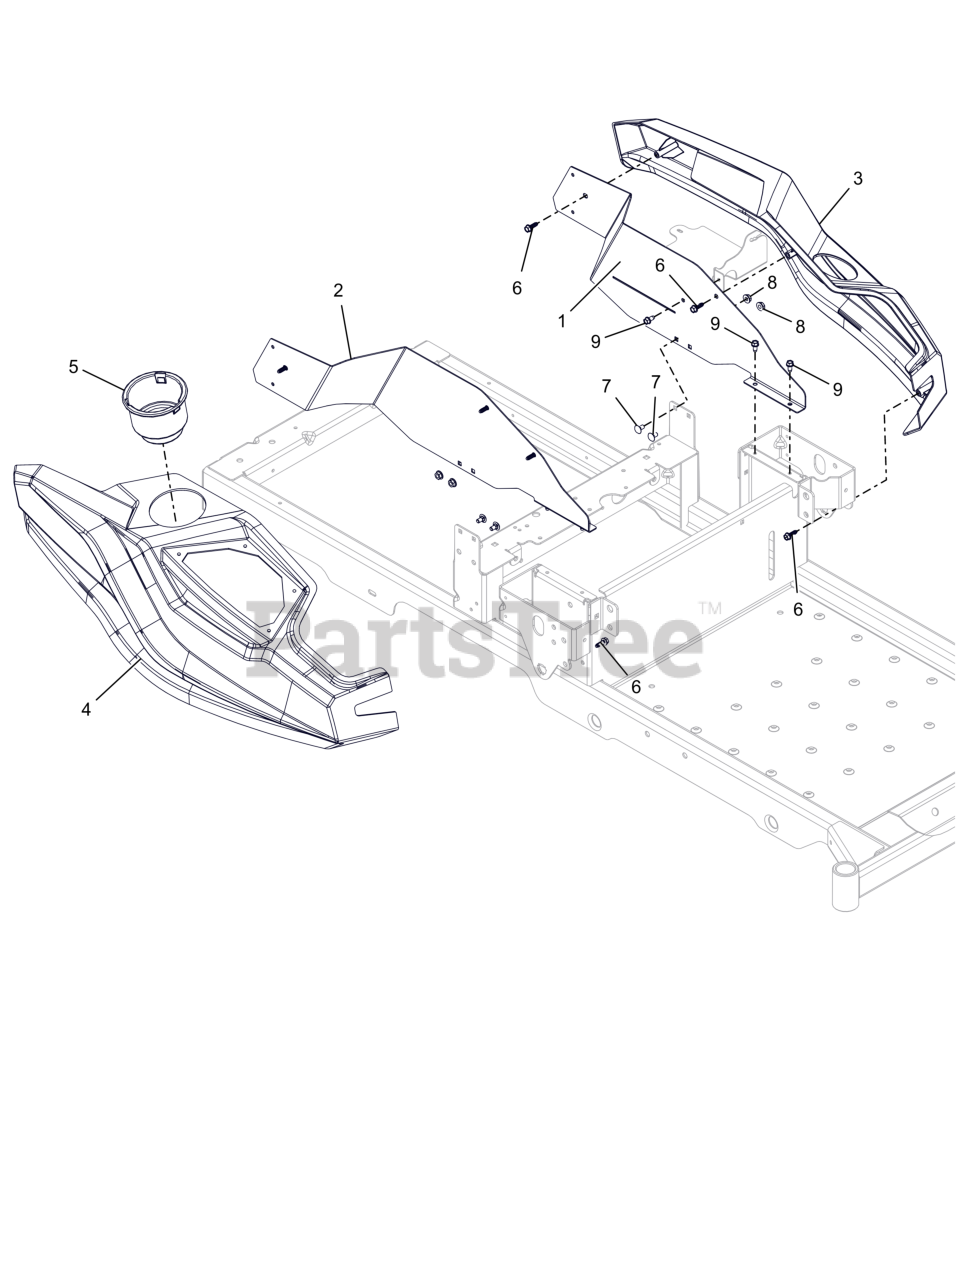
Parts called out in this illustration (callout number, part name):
1	BRKT, FENDER MOUNTING LH (ORANGE)
2	BRKT, FENDER MOUNTING RH (ORANGE)
3	KIT-FENDER WITH DECAL
4	FENDER, RH - ZOOM
5	CUPHOLDER, SNAP-IN 3.75OD
6	SCR, PLASTITE .25-10X.75 ZCC
7	BLT, RHSN .25-20X.500 G5 ZCC
8	NUT-LK-CTR-FLG .25-20 ZC120
9	SCR-TAP .25-20X.50 HWH ZCC
